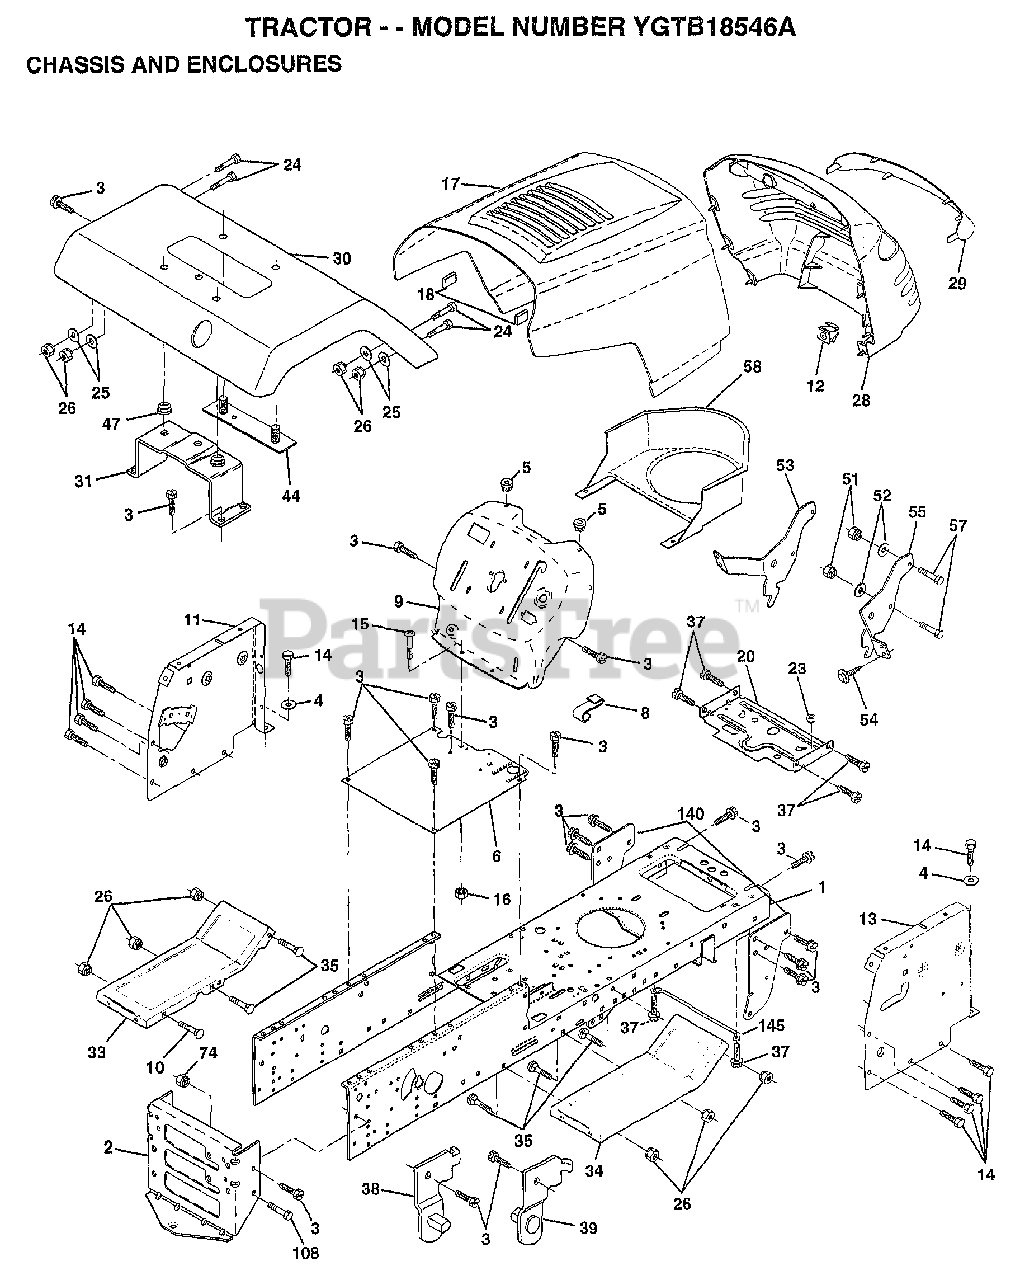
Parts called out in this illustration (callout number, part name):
1	CHASSIS.STAMPING
3	SCREW
4	WASHER
5	BUMPER-HOOD/DASH
6	SADDLE
8	"CLIP,INSULATOR"
9	DASH.PANEL.ASSY
11	PANEL ASM DASH LH
12	CLIP.TINNERMAN
13	PANEL DASH RH
14	SCREW LT
15	SCREW
17	"HOOD W/TRIM,MS428"
20	"STRAP-TORQUE,RH"
24	BOLT
25	WASHER
26	NUT
28	GRILL
29	GRILLE.LENS
30	"FENDER WS,FTK"
31	BRKT.ASM.FENDER
33	FOOTREST PNT LH
34	FOOTREST.RH.LT/GT
35	BOLT
36	PAL NUT LT
37	SCREW LT
38	BRACKET ASM LH
39	BRACKET ASM RH
43	SCREW
44	STRAP ASM FENDER
45	BEZEL.ASM.
47	NUT-PUSH YT
50	DASH.SUPT.YP/HUSQ
51	NUT
52	WASHER
53	BRACKET.GRILLE.LH
54	SCREW.HEX.WS.HD
55	BRACKET.GRILLE.RH
56	EXT DASH LTYT
58	DUCT.AIR.B&S.18HP
64	DASH.LOWER.LT
66	"PLATE DASH,SLKSCR"
67	WASHER
77	SCREW
79	WELDNUT
80	HOOD LATCH T
82	SCREW
83	SPACER LT
86	"PANEL ASM SIDE,RH"
87	"PANEL ASM-SIDE,LH"
90	WASHER PM
92	LOCKWASHER
135	SCREW.10-24X3/8.
136	ACORN NUT RB
137	SNAP CAP LT
138	WASHER LT
139	BKT.SPT.HOOD/PANL
140	BRKT SUSPENSION
145	"ROD POVOT,CHASSIS"
152	SCREW
